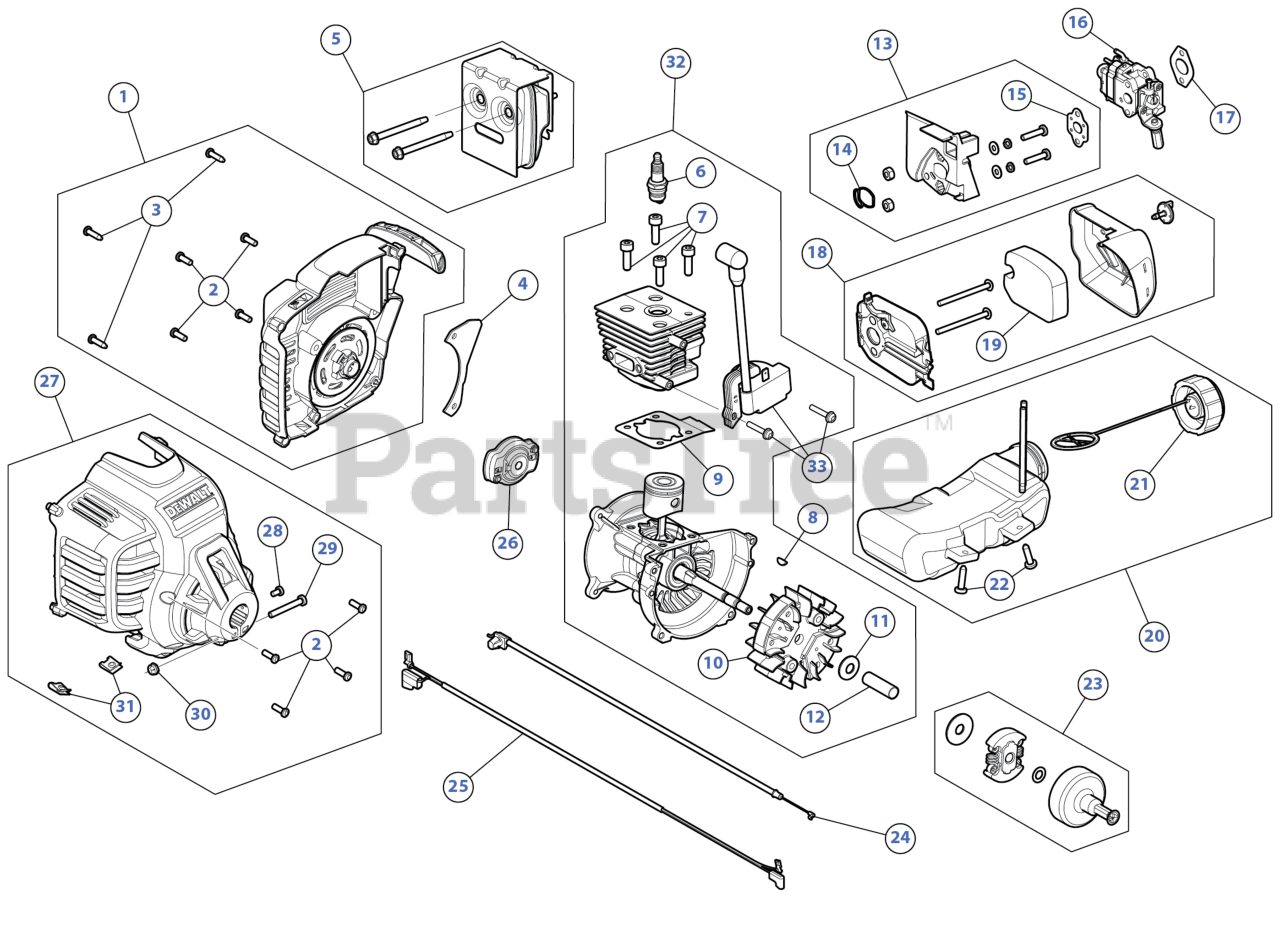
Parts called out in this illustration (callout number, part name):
1	STARTER HOUSING 27CC
2	SCREW #10-24X11/16 T-25
3	SCREW 8-16 x 3/4
4	STARTER GUARD
5	MUFFLER ASSEMBLY
6	SPARK PLUG
7	SCREW 1/4 x 20 x .8125
8	WOODRUFF KEY #403-.125 x .375
9	GASKET CYL
10	FLYWHEEL ASSEMBLY 27CC
11	BELL WASHER
12	SPACER
13	INTAKE ASSEMBLY
14	O-RING
15	CARBURETOR GASKET
16	CARBURETOR:27CC TRIM ROT
17	GASKET CARB
18	AIR CLEANER
19	AIR FILTER
20	FUEL TANK (W/LINE & CAP)
21	FUEL CAP
22	SCREW:10-6 x .75
23	SMALL CLUTCH ASSEMBLY W/SMALL DRUM
24	THROTTLE CABLE
25	LEAD WIRES
26	PAWL ASSEMBLY AC5
27	CLUTCH COVER
28	SCREW, 8-32 x .312 P
29	SCREW
30	HEX NUT
31	NUT, TINNERMAN U-T
32	SHORTBLOCK
33	MODULE 27CC
